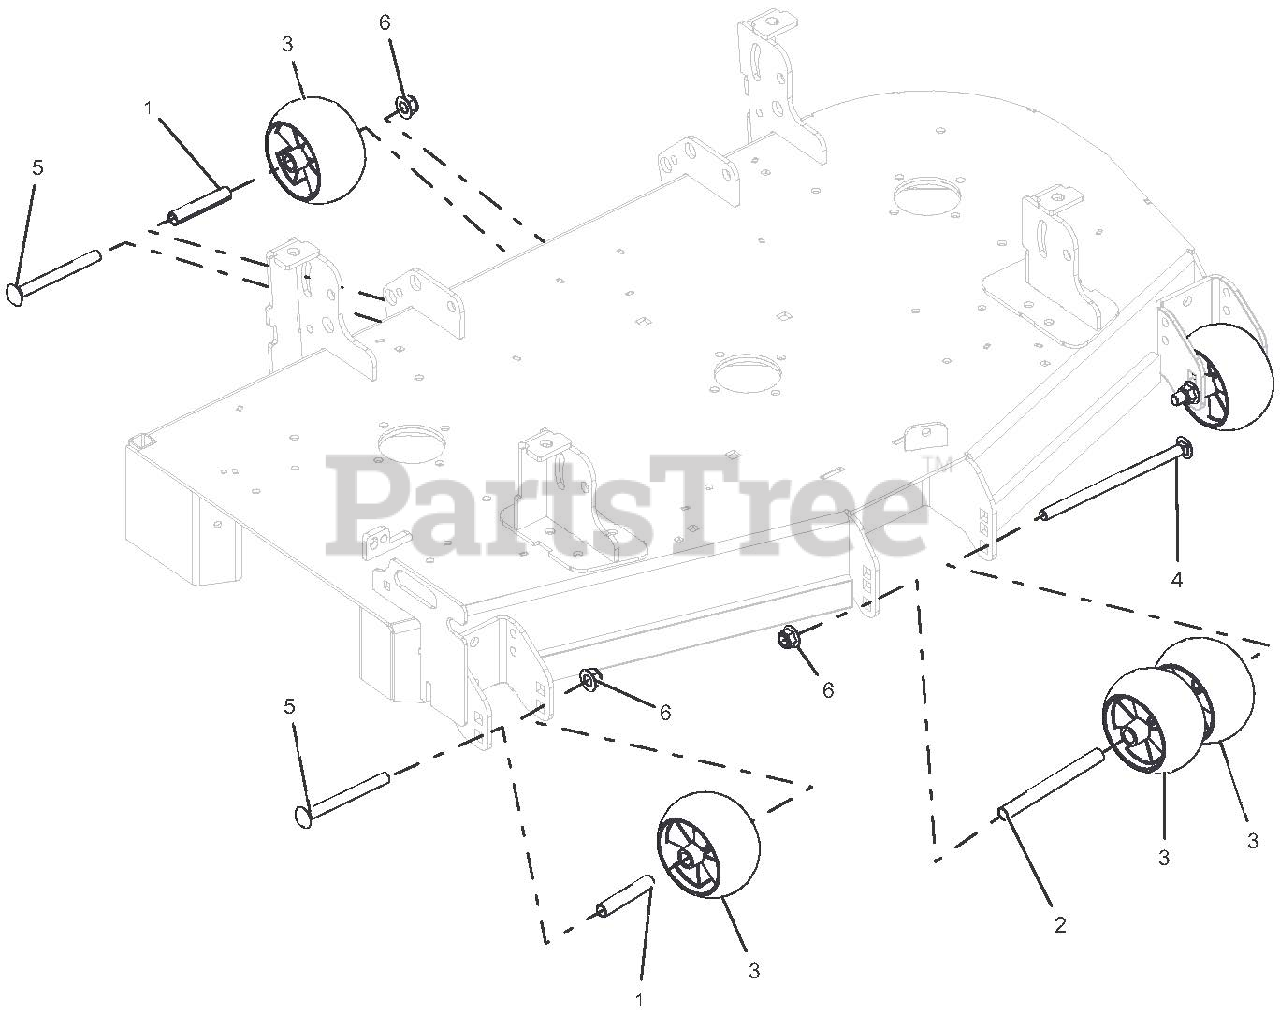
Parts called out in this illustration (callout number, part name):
1	SPACER, .510X.625X3.35
2	SPACER, .510 X .625 X 6.50
3	ANTI-SCALP WHEEL - 5X3 CTR
4	BLT-RDHDSQNK .50-13X8.50 Y
5	BLT-RDHDSQNK .50-13X5.00 G5 YWZC
6	NUT-LK-NYL-FLG .50-13 YWZC
